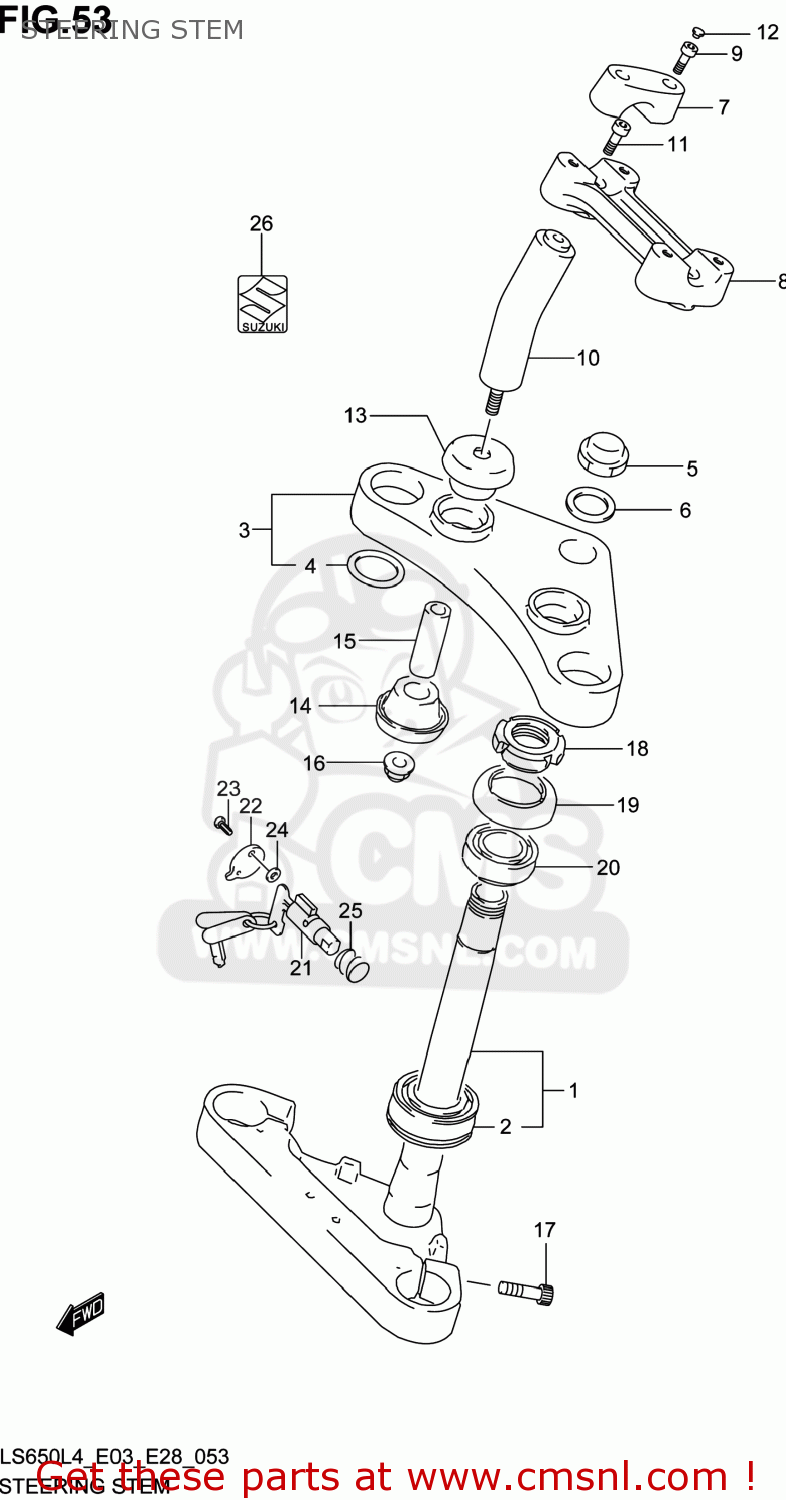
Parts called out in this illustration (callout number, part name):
1	STEM,STEERING
2	BEARING(30X55X17)
3	HEAD,STEERING STEM
4	WASHER,STEM HEAD,LOWER
5	NUT,CAP
6	WASHER(22.5X32X1.6)
7	HOLDER,HANDLE UPR
8	HOLDER,HANDLE LWR
9	BOLT
10	ARM
11	BOLT
12	CAP(OD:14.5)
13	CUSHION,UPR
14	CUSHION,LWR
15	SPACER(10.2X14X46)
16	NUT
17	BOLT
18	NUT,STEERING STEM(25X44X10)
19	SEAL,STEERING UPR DUST
20	BEARING(25X47X15)
21	LOCK ASSY,STEERING
22	CAP,STEERING LOCK
23	PIN,STEERING LOCK
24	WASHER,STEERING LOCK
25	SPRING,STEERING LOCK
26	EMBLEM,"S"
